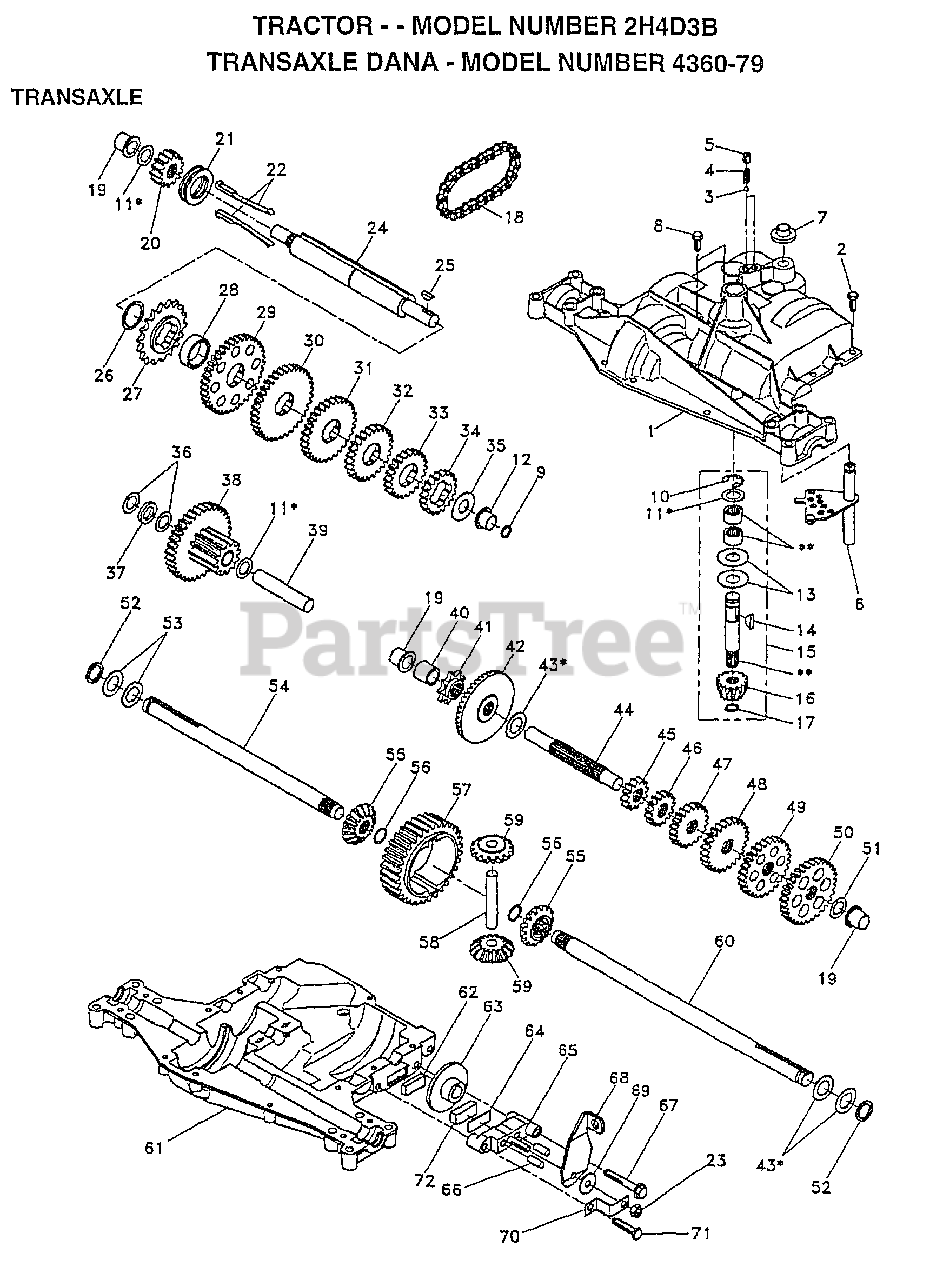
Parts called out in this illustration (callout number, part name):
1	HOUSING UPPER TRN
4	"SPRING, DETENT LT"
5	"SCREW, SET LT"
6	KIT SHIFTER ASM
7	SHIFTER BOOT
8	SCREW TAP W/SEAL
9	SQUARE RING
11	ASM KIT SHIM 4689
12	BEARING FLAN-DANA
13	WASHER T
14	KEY WOODRUFF-DANA
15	AS KIT INPUT SHFT
16	PINION 14T T
17	"RING,RETAINING LT"
18	"CHAIN,24 PTCH LT"
19	BEARING.FLNG.5510
20	GEAR SPUR 14 TTH
21	COLLAR CLUTCH
22	ASM KIT CLTCH KEY
23	NUT.LOCK.5/16-24
24	SHAFT INTERM DANA
25	WOODRUFF KEY
26	"RING,RETAINING LT"
27	SPROCKET 18T T
28	SPACER YT
29	GEAR SPUR 37 TTH
30	GEAR SPUR 35 TTH
32	GEAR 25T LT
33	GEAR SPUR 22 TT
34	SPUR GEAR 19T
35	"WASHER, PLAIN LT"
36	WASHER 025
37	SPACER
38	ASSM GEAR COMB
39	SHAFT IDLER
40	SPACER T
41	SPROCKET 9T LT
43	ASM KIT SHIM
44	SHAFT T
45	GEAR SPUR 12 TTH
46	GEAR SPUR 15 TTH
48	"GEAR, SPUR 25T LT"
49	GEAR 28T T
50	"GEAR, SPUR 31T LT"
51	WASHER 060
52	NEOPRENE WASHER
53	WASHER 031
55	GEAR 15T T
56	"RING,RETAINING LT"
58	SHAFT T
59	GEAR 1ST T
61	HOUSING LOWER TNS
62	PUCK T
63	BRAKE DISC. T
64	SPACER LT
66	PIN T
69	WASHER LT
71	"SCREW, TAPPING LT"
72	PUCK T
